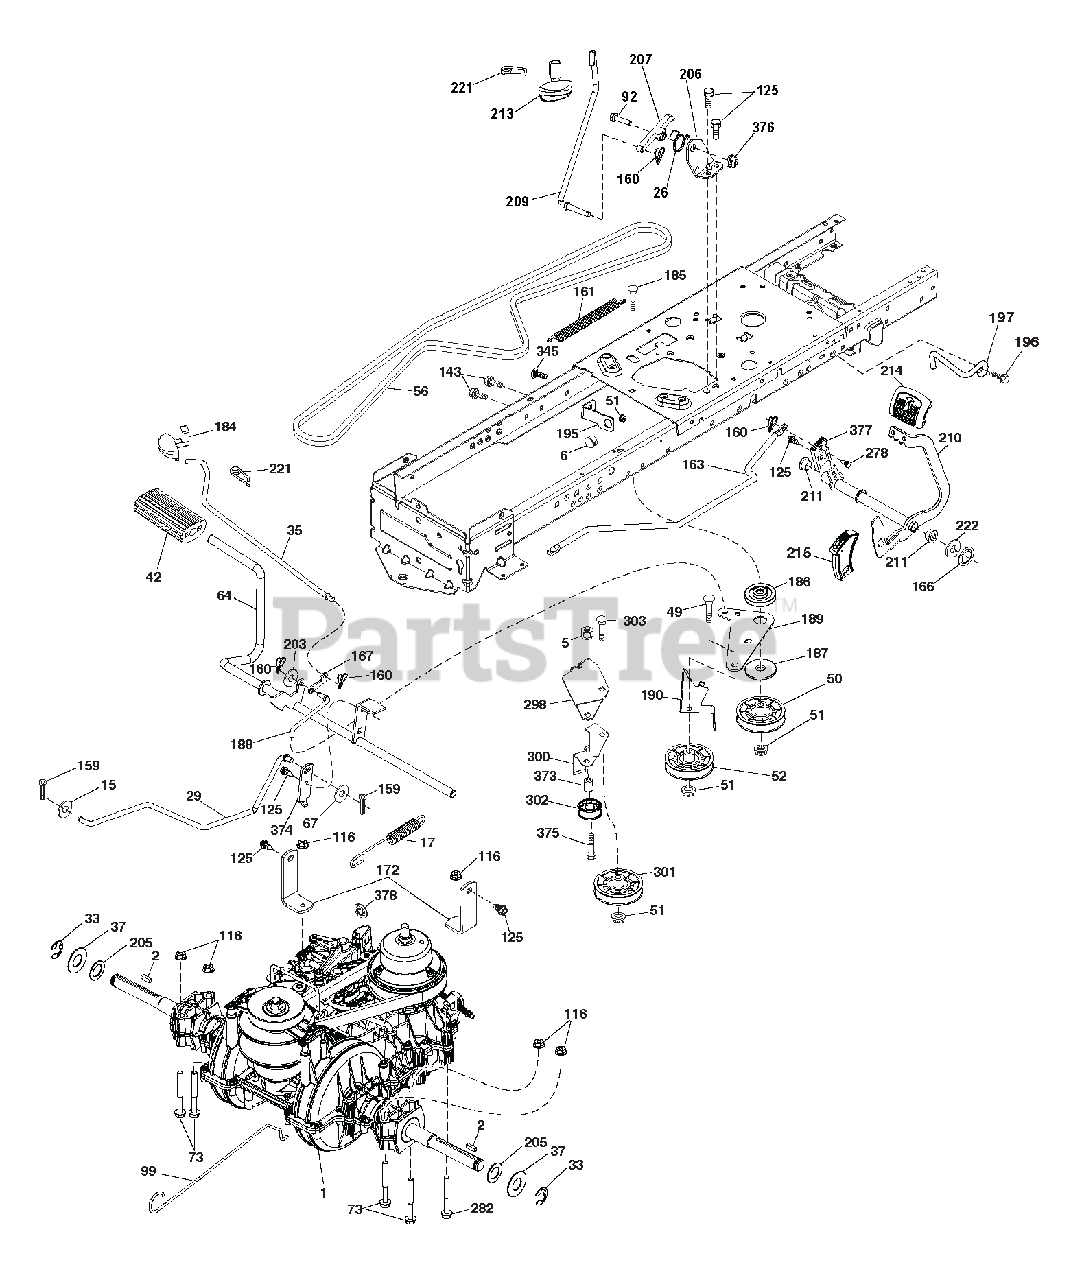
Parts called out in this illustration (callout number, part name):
1	TRANSMISSION, GENTRANS VATR (580486201)(ORDER PARTS FROM TRANSAXLE MANUFACTURER.)
2	KEY.SQUARE.2.0 X .1845/.1865
5	Nut, Hex, Crownlock 3/8-16
6	Bushing Snap Nyl Blk Fuel Line
15	WASHER.13/32 X 13/16 X 16 GA.
17	SPRING.BRAKE.K46.GREEN
26	SPRING.RETURN.CRUISE
29	ROD.BRAKE
33	E-RING.#5133-75
35	ROD.BRAKE.PARKING
37	WASHER.HARDEN..793 X 1.637X060
42	COVER PEDAL BLK ROUND
49	BOLT.RDHD.3/8-16UNCX1-3/4.GR5
50	IDLER.FLAT.910"OFFSET
51	Nut, Hex, Flangelock 3/8-16
52	IDLER.V-GROOVE.910"OFFSET
56	BELT.DRIVE.100.97"
64	SHAFT ASM. PEDAL BRAKE
67	Washer 13/32 x 13/16 x 12 Ga.
73	BOLT.HEX.FLGHD.5/16-18.GR.5
92	Bolt, Hex Head 5/16-18 x 1-1/4
99	ROD.BYPASS
116	Nut, Lock Hex Flange 5/16-18 u
125	SCREW.5/16-18X3/4.SMGML.TAP/BL
143	SCREW.THDROL.5/16-18 X 1/2TYTT
159	PIN.COTTER.1/8 X 3/4.CAD.
160	RETAINER.CLIP(M).DIA.290
161	SPRING.RETURN.CLUTCH.6.75
163	ROD CONTROL PEDAL
166	NUT PUSH .625
167	LATCH.BRAKE.PARKING
172	STRAP TORQUE VARIATOR
184	HANDLE.PARKNG.BRAKE.LT.TEX.667
185	BOLT.RDHD.3/8-16UNC X2-3/4 GR5
186	SPACER.RETAINER
187	WASHER.13/32 X 2 X 10 GA.
188	LINK.CLUTCH.GROUND DRIVE
189	BELLCRANK.GROUNDRIVE.NSTG/NSTL
190	KEEPER.BELLCRANK.DRIVE.GROUND
195	BRACKET.BRAKE
203	Washer 11/32 x 11/16 x 16 Ga.
205	WASHER.25/32 X 1-5/8 X 16GA.
206	BRACKET MOUNT LATCH CRUISE
207	LATCH CONTROL CRUISE
209	ROD.CONTROL.CRUISE
210	WELDMENT PEDAL
211	BEARING.NYLON.BLK..629 ID.
213	KNOB.CONTROL.CRUISE
214	PAD PEDAL FORWARD
215	CAP PEDAL REVERSE
221	RETAINER.SPRING.CLIP.HANDLE
222	WASHER.21/32X1-1/4.10GA.N/PLTD
278	BOLT CRUISE VARIATOR
282	BOLT.HEX. 5/16-18 X 3 GR. 5
298	Bracket Mount Idler
300	Keeper Idler Rear
301	Pulley Idler V-Groove
302	PULLEY,IDLER.FLAT
303	Bolt RDHD SQNK 3/8-16 x 2-1/4
345	Bolt Rdhd Sht Sqnk 3/8-16 x 3/
373	SPACER.IDLER
374	ARM.BRAKE.CONTROL
375	BOLT.HEX.HS.3/8-16.UNCX2-1/4
376	Locknut, Hex 5/16-18
377	GEAR SECTOR CONTROL CRUISE
378	NUT PUSH
